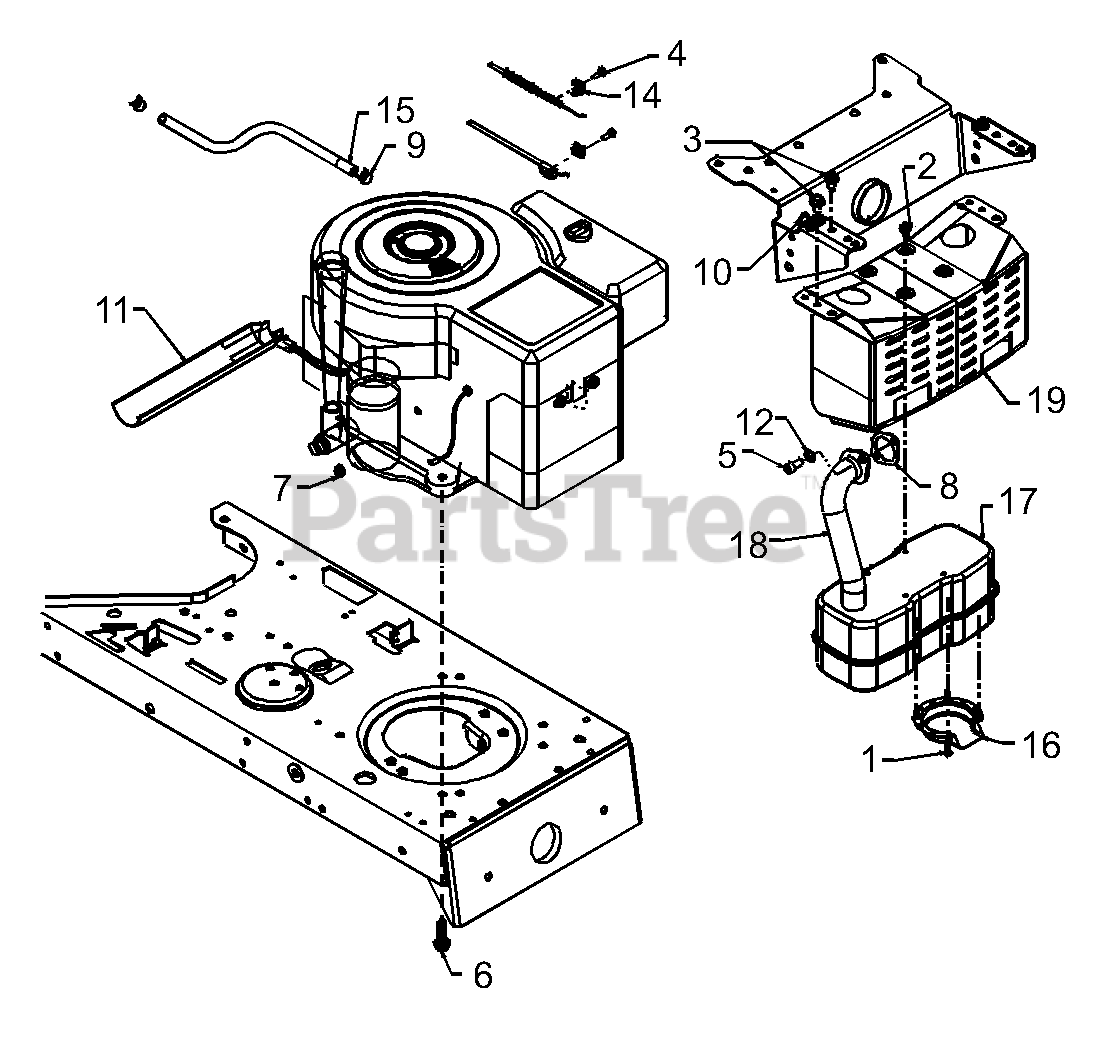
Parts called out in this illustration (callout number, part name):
1	Hex Tap Scr. #8-32 x .38" Lg.
2	Hex TT-Tap Scr. 1/4-20 x .5" Lg.
3	Hex TT-Tap Scr. 5/16-18 x .62"
4	Hex Wash. Scr. #10-32 x .62"
5	Socket Head Scr. 5/16-18 x .62"
6	Hex TT-Tap Scr. 3/8-16 x 1.25"
7	Hex Sems Scr. 1/4-20 Thd.
8	Gasket
9	Hose Clamp
10	Clamp
11	Oil Drain Sleeve
12	Lock Washer 5/16" I.D.
14	Casing Clamp
15	Fuel Line 12" Lg.
16	Muffler Deflector
17	Muffler
18	Exhaust Pipe
